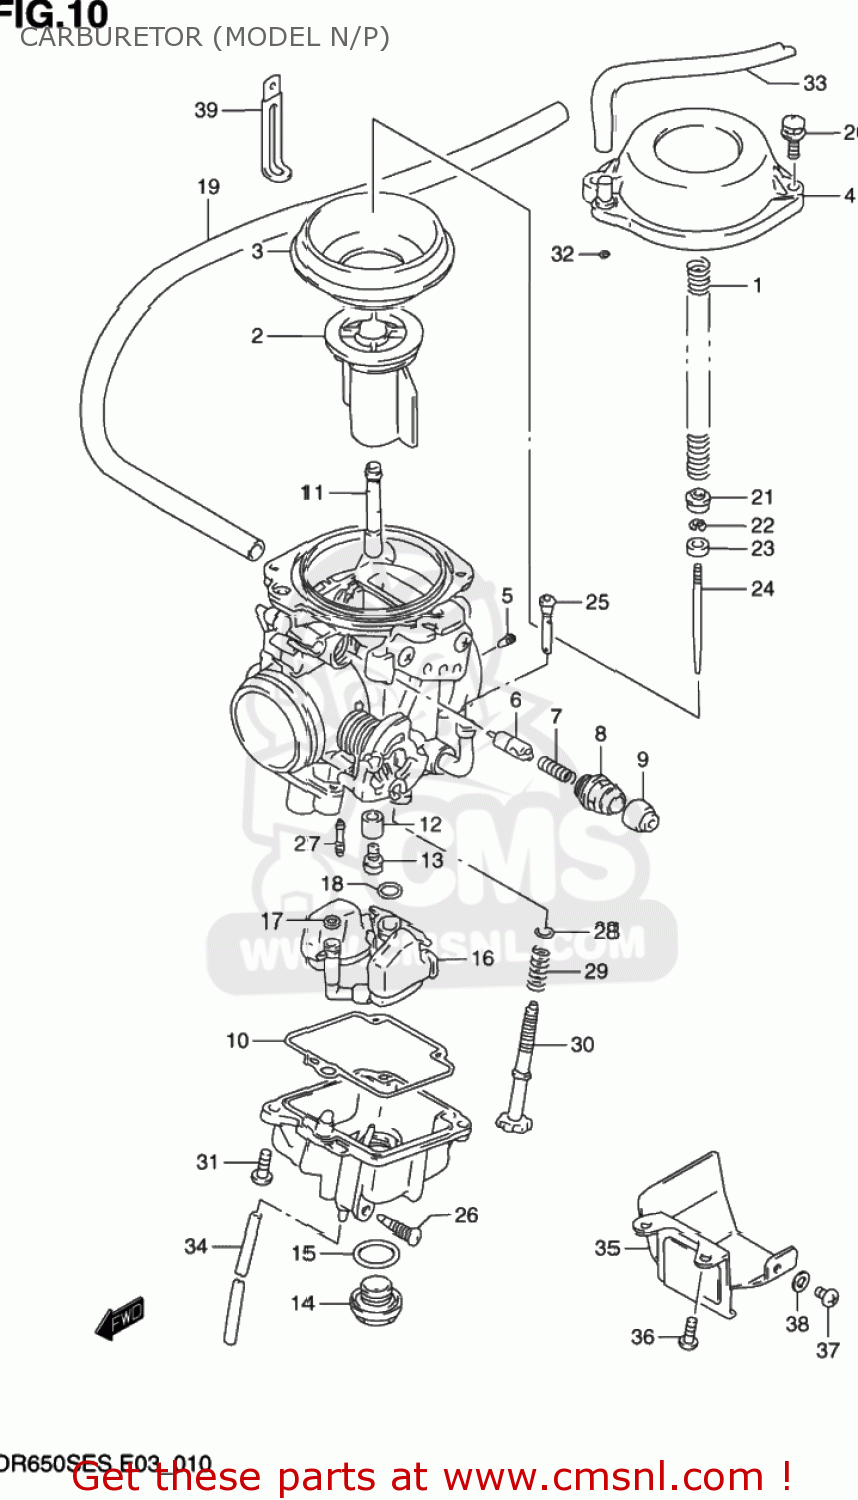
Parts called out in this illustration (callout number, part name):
1	SPRING
2	VALVE,PISTON
3	DIAPHRAGM
4	COVER,DIAPHRAGM
5	JET,AIR
6	PLUNGER
7	SPRING
8	HOLDER,GUIDE
9	CAP
10	GASKET,FLOAT CHAMBER (NAS)
11	JET,NEEDLE(Y-2)
12	RING
13	JET,MAIN(137.5)
14	SCREW,GUIDE
15	O RING,DRAIN PLUG
16	FLOAT/NEEDLE VALVE ASSEMBLY
17	O RING
18	O-RING,NEEDLE VALVE
19	HOSE
20	SCREW
21	RING
22	CLIP,NEEDLE
23	RING
24	NEEDLE,JET
25	FILTER
26	SCREW,DRAIN
27	JET,PILOT(52.5)
28	WASHER
29	SPRING
30	SCREW
31	SCREW
32	O RING
33	HOSE
34	HOSE
35	PLATE ASSEMBLY
36	SCREW
37	SCREW
38	WASHER
39	CLAMP
